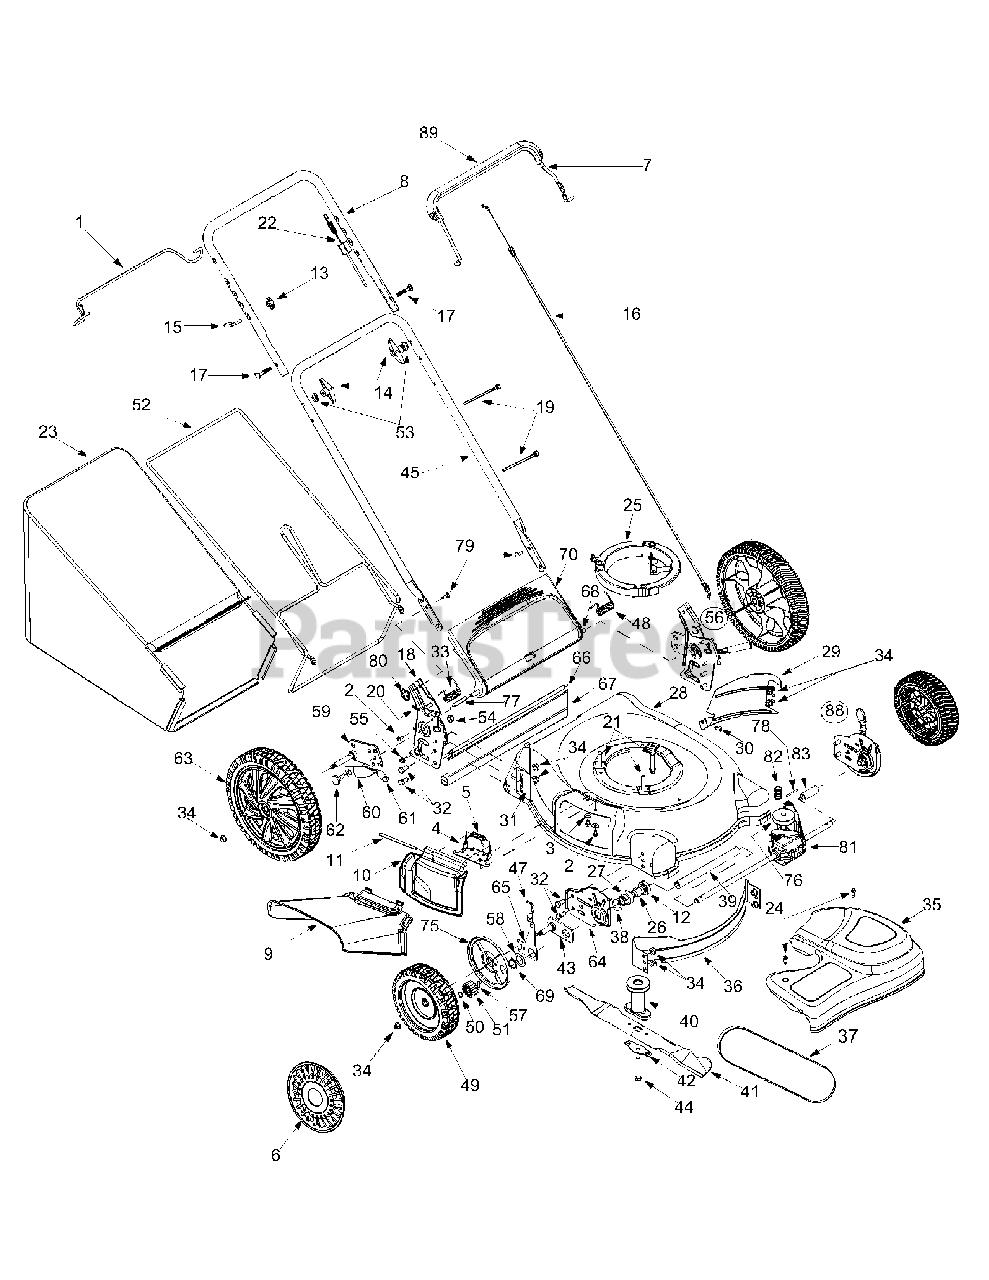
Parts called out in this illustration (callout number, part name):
1	Lower Bail Handle
2	TT Screw 1/4-20 x 0.5
3	Bell Washer.265 x 0.75
4	Deflector Chute Adapter
5	Torsion Spring
6	Hub Cap
7	Blade Control Handle
9	Chute Deflector
10	Mulch Plug Complete
11	Hinge Pin
12	Bearing Retainer
13	Handle Knob
14	Handle Knob
15	Eye Bolt
16	Control Cable - 37.75"
16	Control Cable - 40.75"
17	Carriage Bolt 5/16-18 x 2.0
18	RH Handle Bracket
18	LH Handle Bracket
19	Cable Tie
20	Cotter Pin
21	Self-Tapping Sems Screw
22	Drive Cable - 50.50"
23	Grassbag Assembly
24	Shoulder Screw # 12 -24
25	Engine Spacer
26	Bearing Sleeve
27	Bearing Support
28	21" Deck
29	LH Rear Baffle
30	Screw AB: 1/4-14:.625
31	RH Rear Baffle
32	Hex Screw 3/8-16 x.75
33	Torsion Spring RH
34	Flange Lock Nut 3/8-16
35	Transmission Cover (Black)
36	Front Baffle
37	V-Belt
38	Wave Washer
39	Sleeve Spacer 9.04" Lg.
40	Blade Adapter w/ Pulley
41	21" Mulching Blade
42	Blade Bell Support
43	Pivot Plate Assembly
44	Hex Screw 3/8-24 x 2.50
45	Lower Handle
47	Adjustment Knob
48	Torsion Spring LH
49	Wheel 8 x 2.125
50	Snap Ring
51	Gear 14T RH FWD
51	Gear 14T LH FWD
52	Grass Bag Frame
53	Saddle Washer
54	Hex Flange Lock Nut 3/8-16
55	TT Scr. w/Washer 1/4-20 x.625
56	RH Handle Bracket Assembly
56	LH Handle Bracket Assembly
57	Dowel Pin
58	Washer
59	Pivot Arm Assembly - RH
59	Pivot Arm Assembly - LH
60	Rear Spring Lever
61	Foam Grip
62	Shoulder Scr.500 Dia. x.434
63	Wheel, 12 x 2.125
64	Height Adjuster Plate - RH
64	Height Adjuster Plate - LH
65	Front Lever - RH
65	Front Lever - LH
66	Wire
67	Rear Trailing Shield
68	Pivot Rod
69	Snap Ring
70	Rear Discharge Door
75	Wheel Dust Cap
76	Input Pulley
77	Spacer.375 x.50 x 1.02" Lg.
78	Roll Pin
79	Carriage Bolt 1/4-20
80	Wing Nut
81	Transmission Assembly
82	Belt Tension Spring
83	Slev. Spacer 2.1" Lg.
88	Height Adjustment Assembly RH
88	Height Adjustment Assembly LH
89	Deluxe Bail Cover
